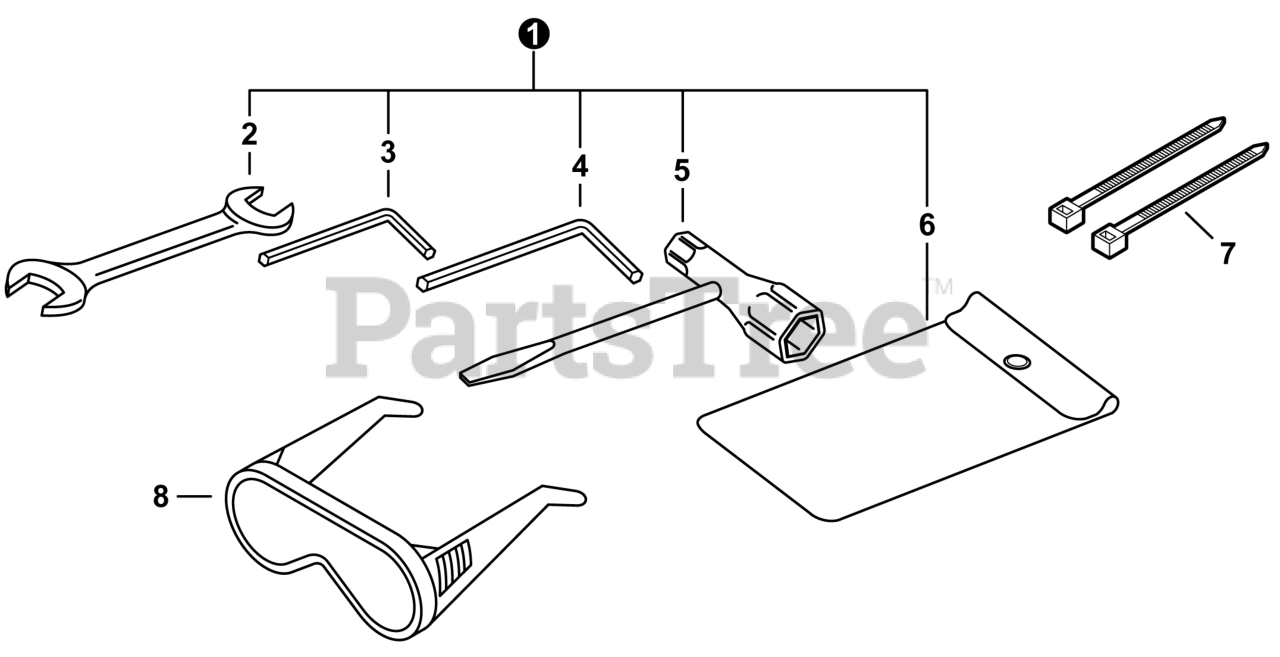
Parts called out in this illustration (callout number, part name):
1	TOOL KIT, SERVICE
2	SPANNER 8x10
3	WRENCH, ALLEN 4 MM
4	WRENCH, ALLEN 5 MM
5	T-WRENCH 17x19 L200
6	BAG, TOOL
7	TIE, CABLE
8	GLASSES, SAFETY
